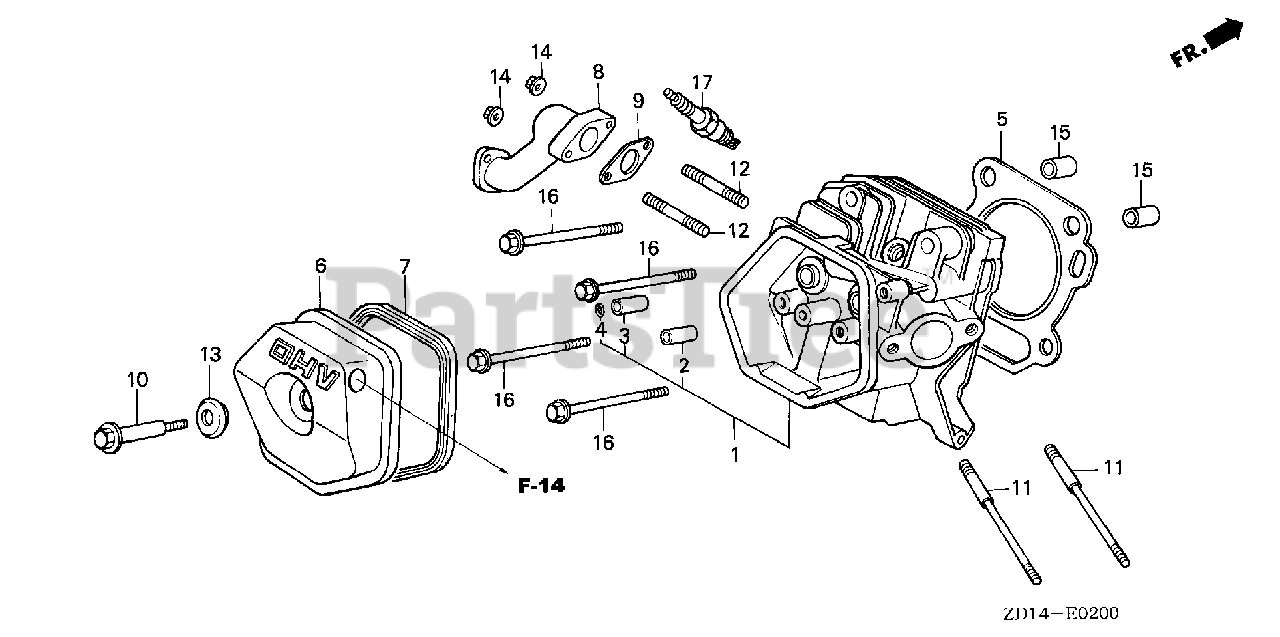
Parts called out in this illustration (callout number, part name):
1	CYLINDER HEAD
2	GUIDE, VALVE (OVER SIZE)
3	GUIDE, EX. VALVE (OVER SIZE)
4	CLIP, VALVE GUIDE
5	GASKET, CYLINDER HEAD
6	COVER KIT, HEAD
6	COVER, HEAD
7	GASKET, HEAD COVER
9	GASKET, EX. PIPE
10	BOLT, HEAD COVER
11	BOLT, STUD (8X106)
12	BOLT, STUD (8X47)
12	BOLT, STUD (8X32)
13	WASHER, HEAD COVER
14	NUT, FLANGE (8MM)
15	PIN, DOWEL (12X20)
16	BOLT, FLANGE (10X80)
17	SPARK PLUG (BPR5ES) (NGK)
17	SPARK PLUG (W16EPR-U) (DENSO)
